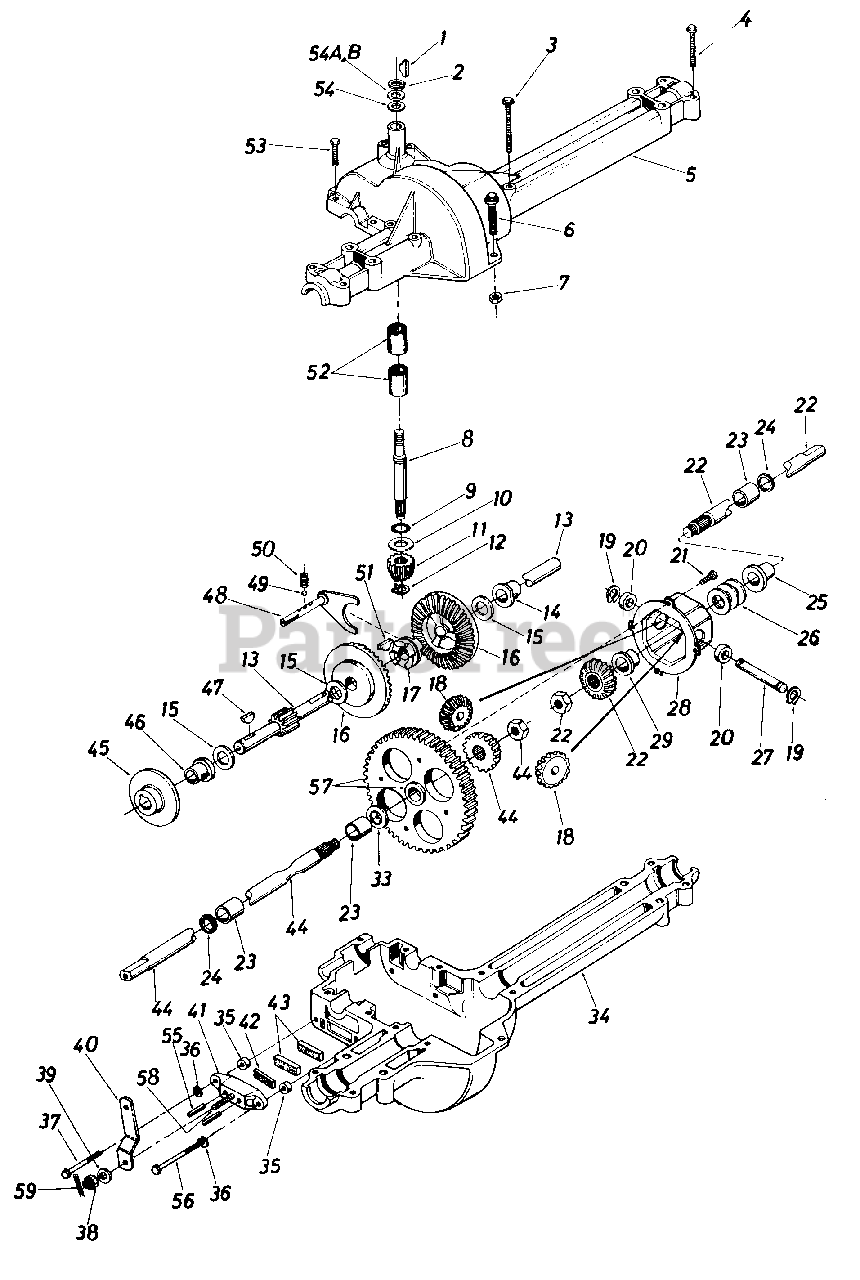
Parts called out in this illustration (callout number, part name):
1	#4 Hi-Pro Key 3/32 x 5/8" Dia.
2	Snap Ring .625" Shaft
3	Hex Bolt 1/4-20 x 1.75" Lg.
4	Hex Bolt 5/16-18 x 2.5n
5	Upper Housing
6	Hex Fl-Bolt 1/4-20 X .88" Lg.
7	Hex Nut 1/4-20 Thd.
8	Input Shaft
9	Square Seal 5/8" I.D.
10	Thrust Washer 5/8" I.D. x 1.25" O.D.
11	Pinion Input 14T
12	Retaining Ring 7/16" Ext.
14	Flange Brg. 5/8" l.D. x 4/5" Lg.
15	Fl-Wash.
16	Bevel Gear 42T
17	Clutch Collar
18	Miter Gear 1 5T (H .D.)
19	Snap Ring
20	Thrust Bearing 1/2" l.D. x l.0" O.D.
21	Pan Head Scr. 1/4-20 X .50" Lg. w/Patch
22	Axle R.H. Ass'y.
23	Sleeve Bearing 3/4" l.D. x 1.0" Lg
24	Oil Seal 3/4" l.D.
25	Flange Bearing 3/4" l.D. x 15/16" Lg.
26	Fl-Wash. .760" l.D. x 1.49" O.D.
27	Cross Shaft
28	Differential Housing Ass'y.
33	Fl-Wash. .760" l.D. x 1.49n
34	Lower Housing
35	Spacer .53" O.D. x 3/8" Lg.
36	L-Wash. 1/4" l.D.
37	Hex Bolt 1/4-20 x l.5On Lg. (Grade 5)
38	Castle Nut 5/16-24 Thd.
39	Fl-Wash. 344" I.D. x .375" O.D.
40	Actuating Arm
42	Puck Plate
43	Brake Puck
44	Axle L.H. Ass'y.
46	Flange Bearing s/sn l.D. x 15/16" Lg.
47	Woodruff Key 3/16 x 5/8 HT
48	Shift Fork Ass'y.
49	Ball Detent .250 Dia.
50	Spring Detent
51	#9 Hi-Pro Key 3/16" x 3/4" Dia. HT
52	Needle Brg. 5/8" l.D. x 1/2" Lg.
53	Hex Bolt 1/4-20 x 1.00" Lg.
54	Fl-Wash. 5/8" l.D. x .030
54A	Fl-Wash. 5/8" I.D. x .040
55	Actuating Pin 5/16" Dia.
56	Hex Bolt 1/4-20 x 2.5O" Lg. (Grade 5)
57	Differential Gear 72T Ass'y. w/Bearing
58	Sq. Hd. Bolt 5/16-24 Thd.
59	Cotter Pin 3/32" Dia. x .Son Lg.
